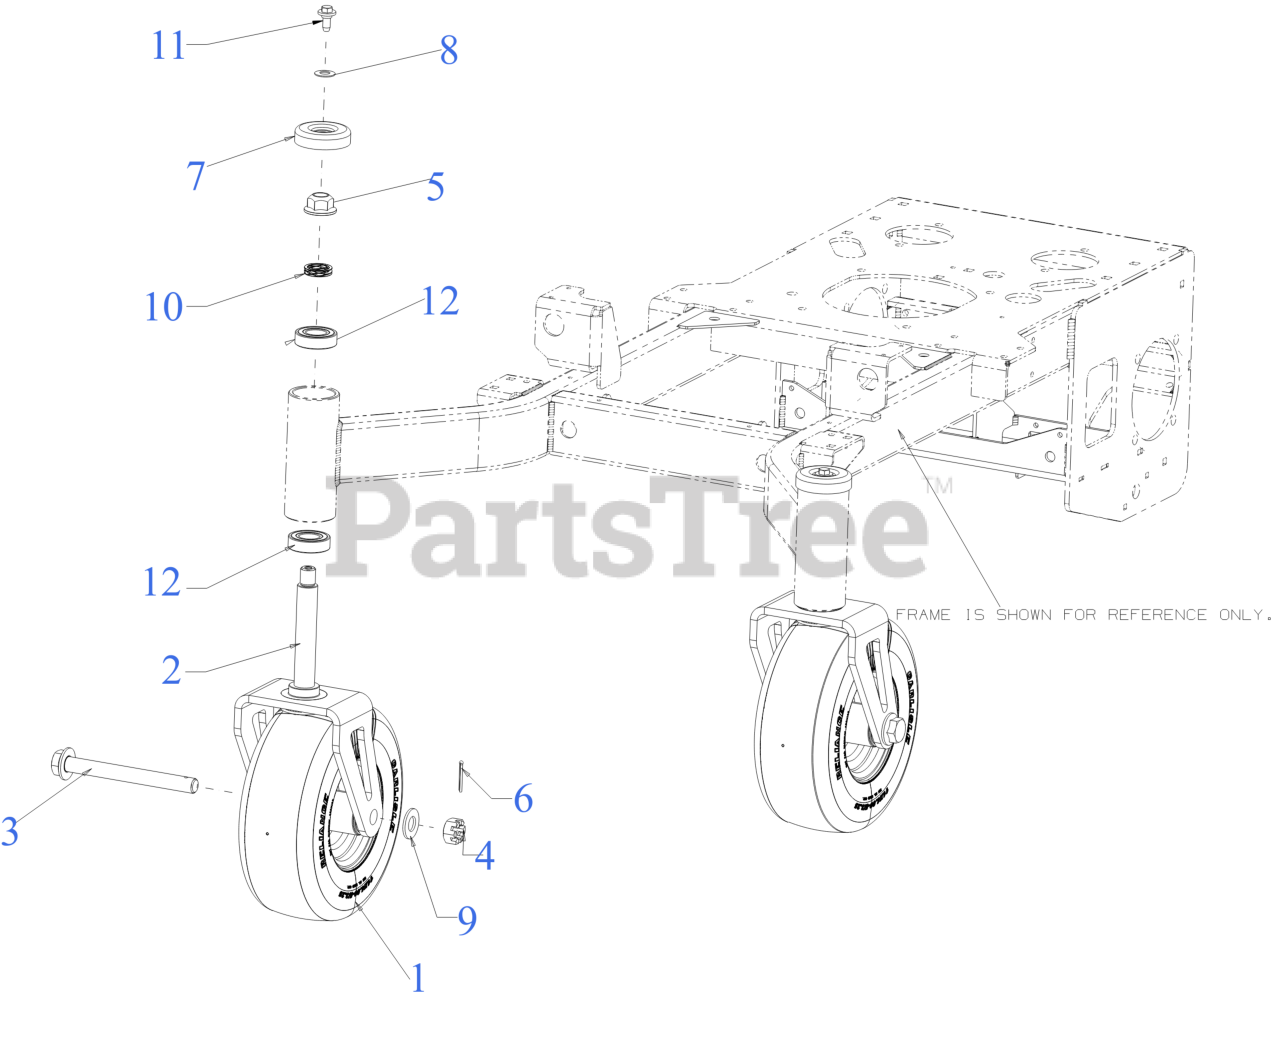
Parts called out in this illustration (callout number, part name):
1	WHEEL ASSEMBLY (11 x 4 - 5 SIMI PNE)
1	SEALED BALL BEARING
2	CASTER YOKE
3	HEX FLANGE BOLT 3/4-16x7.0 GR5
4	HEX NUT CASTLE 3/4-16
5	FLANGE LOCK NUT 3/4-16 TOP LOCK
6	COTTER PIN-5/32 DIA
7	AXLE CAP 2.5"
8	BELL WASHER
9	FLAT WASHER
10	WAVE WASHER
12	BALL BEARING (1.0 x 52 x 15)
